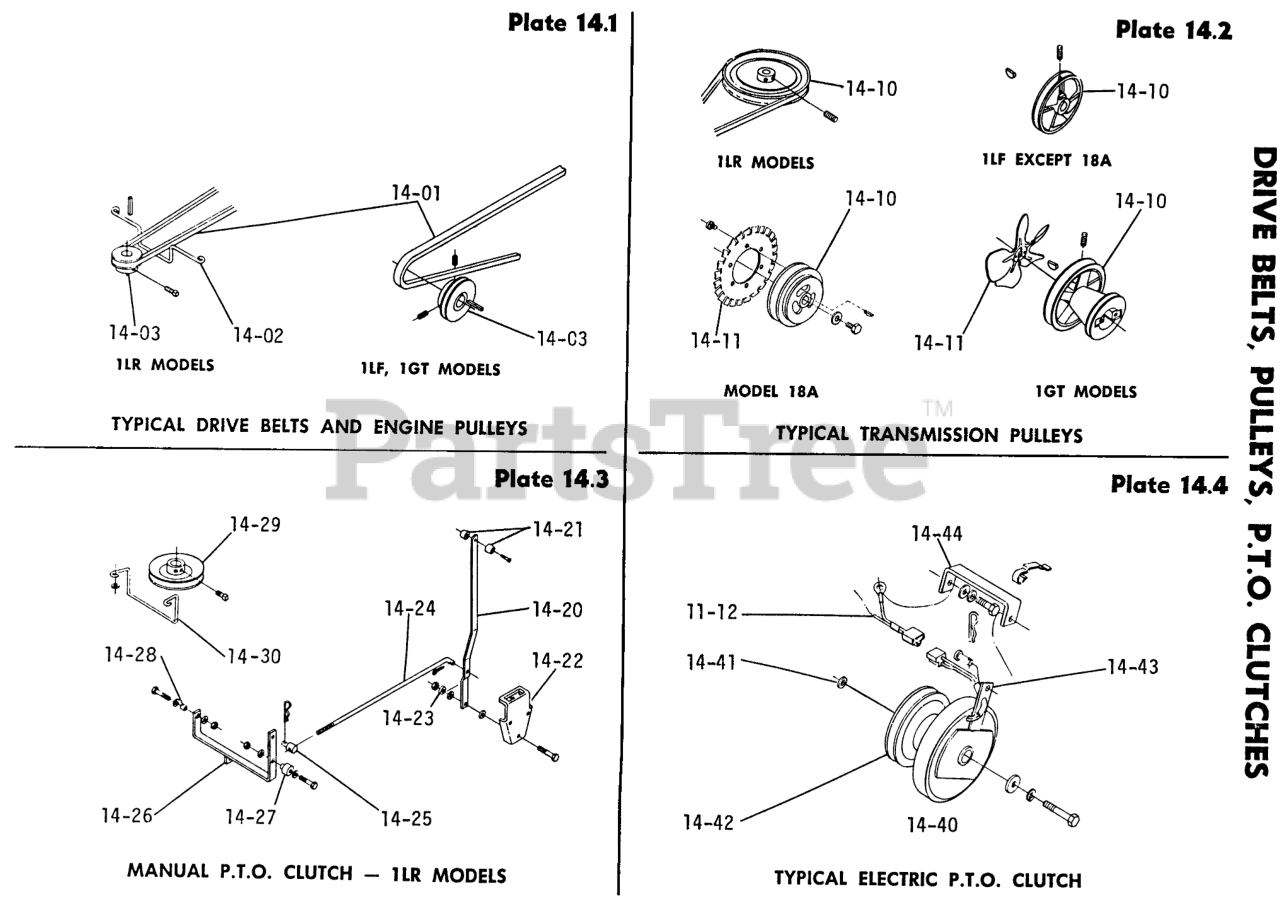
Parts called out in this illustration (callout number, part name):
14-01	V BELT
14-01	V-BELT
14-03	Set Scew, Sq. Head
14-03	Pulley-Engine Main Drive
14-03	PULLEY
14-03	Set Screw
14-10	KEY WOODRUFF
14-10	Set Scew, Sq. Head
14-10	PULLEY
14-10	Pulley
14-10	Key
14-10	WOODRUFF KEY
14-10	Set Screw 5/16-18 x 5/16
14-10	Bolt, 1/4-20 x 3/4 Nylok
14-11	Screw, #8-32
14-11	Lockwasher
14-11	Screw Washer Assy. 1/4-20 x 5/16
14-21	KNOB
14-21	Bolt #10-24 x 1 1/4
14-22	Bracket Engage Lever
14-23	Washer-Rubber
14-23	Bolt, 3/8-16 x 1/2
14-23	Washer
14-24	Hairpin
14-25	Hairpin
14-26	Engaging Link
14-27	Spacer-Engaging Link
14-28	Bolt, 5/16-18 X 7/8
14-28	Bolt 5/16-18 x 1/2
14-28	Nut-Nylok
14-28	Washer
14-29	Set Scew, Sq. Head
14-30	Guide-Belt
14-30	Nut-Nylok
14-30	Washer
14-41	Washer-Spacer
14-43	Pin, rod end-to bracket
14-43	Hairpin
14-44	Bracket Assy.
14-44	Bolt 3/8-16 x 7/8
14-44	Lockwasher
14-44	Bolt, 7/16 14 x 1
14-44	Washer
14-44	Lockwasher 3/8
14.40	Bolt Hex 7/16-20 x 2
14.40	Washer
14.40	Lockwasher-7/16 Ext. Tooth
